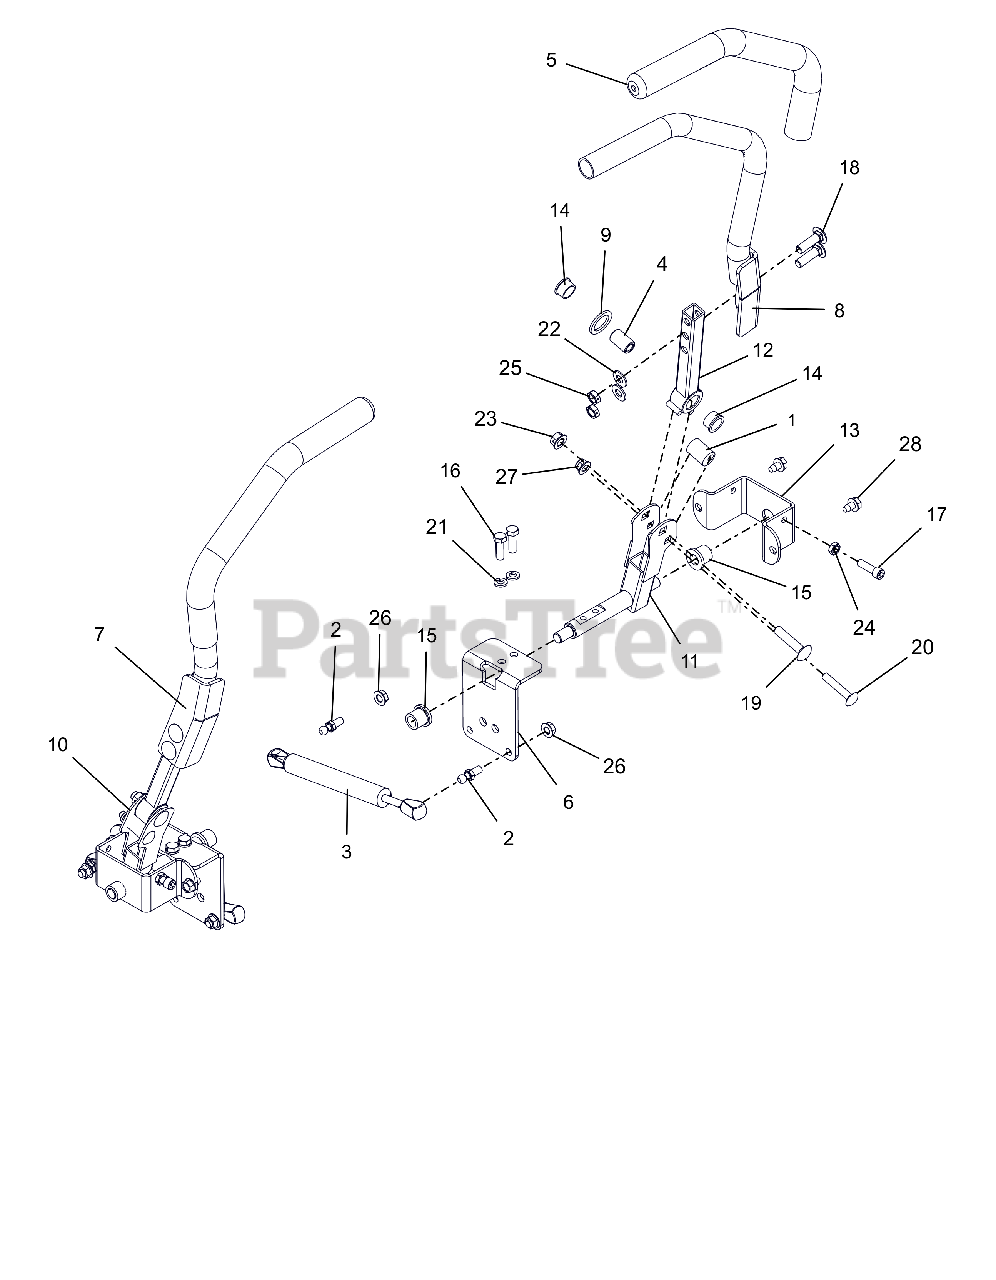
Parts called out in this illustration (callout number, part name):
1	BSHG,ECCEN .328X.750X1.01 PM
2	STUD- BALL
3	DAMPER, STABILUS
4	SPACER, .375X.625X.970 (PM)
5	GRIP, HANDLEBAR 15" FOAM
6	BRKT, STEEERING
7	WLDMT, STEERING HANDLE RH
8	WLDMT, STEERING HANDLE LH
9	WASHER, FRICTION .875X1.25X.10
10	WLDMT,STEERING ARM LOWER RIGHT
11	WLDMT,STEERING ARM LOWER LEFT
12	WLDMT, UPPER CONTROL ARM
13	BRKT, STEERING
14	BSHG-FLG, .625X.75X.450X.875
15	BSHG-FLG .515X.750X.745X1.00NY
16	BLT-HEX .31-18X1.00 GR8 YWZC
17	SCR, SKH .312-18X1.00 G8 SS
18	BLT,RHSSN .38-16X1.25 G5 BFP
19	BLT,RHSSN .38-16X1.75 G5 BFP
20	BLT,RHSSN .31-18X1.75 G5 BFP
21	@WSHR-LK .31X.078 REG YWZC
22	@WSHR-FL-STL.406X.812X.065 YWZ
23	NUT-LK-CTR-FLG .38-16 YWZC
24	NUT- JAM .312-18 YWZC
25	@NUT-LK-CTR-JAM .375-16 YWZC
26	@NUT-LK-TOP-FLG .31-18 YWZC
27	@NUT-LK-NYL-FLG .31-18 YWZC
28	@SCR-TAP .31-18X.50 HWH TR YWZ
